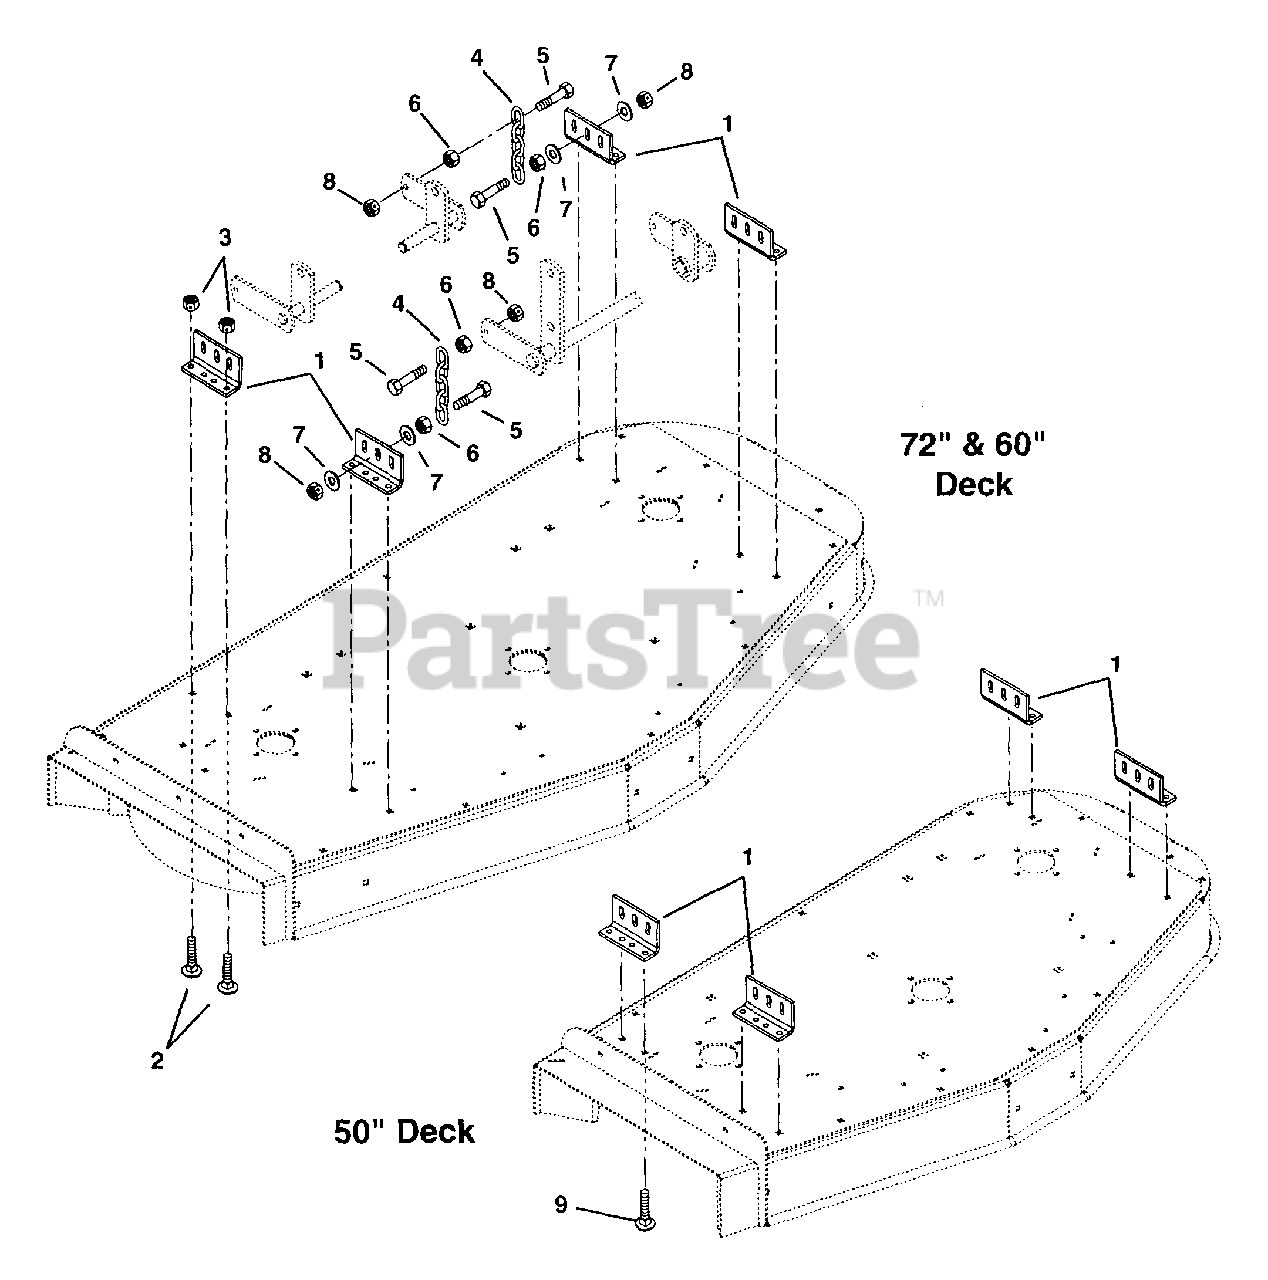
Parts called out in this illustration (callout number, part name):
1	Bracket, Mower Mounting
2	Bolt-Round Head Square Neck .38-16 x 1.25 Grade 2
3	Nut-Locking-Nylon .38-16
4	Chain, Link
5	Bolt-Hex .38-16 x 1.50 Grade 5
6	Nut-Hex .38-16
7	Washer-Flat-Steel .406 x .812 x .065
8	Nut-Locking-Center .38-16
9	Bolt-Round Head Square Neck .38-16 x 1.50 Grade 2
